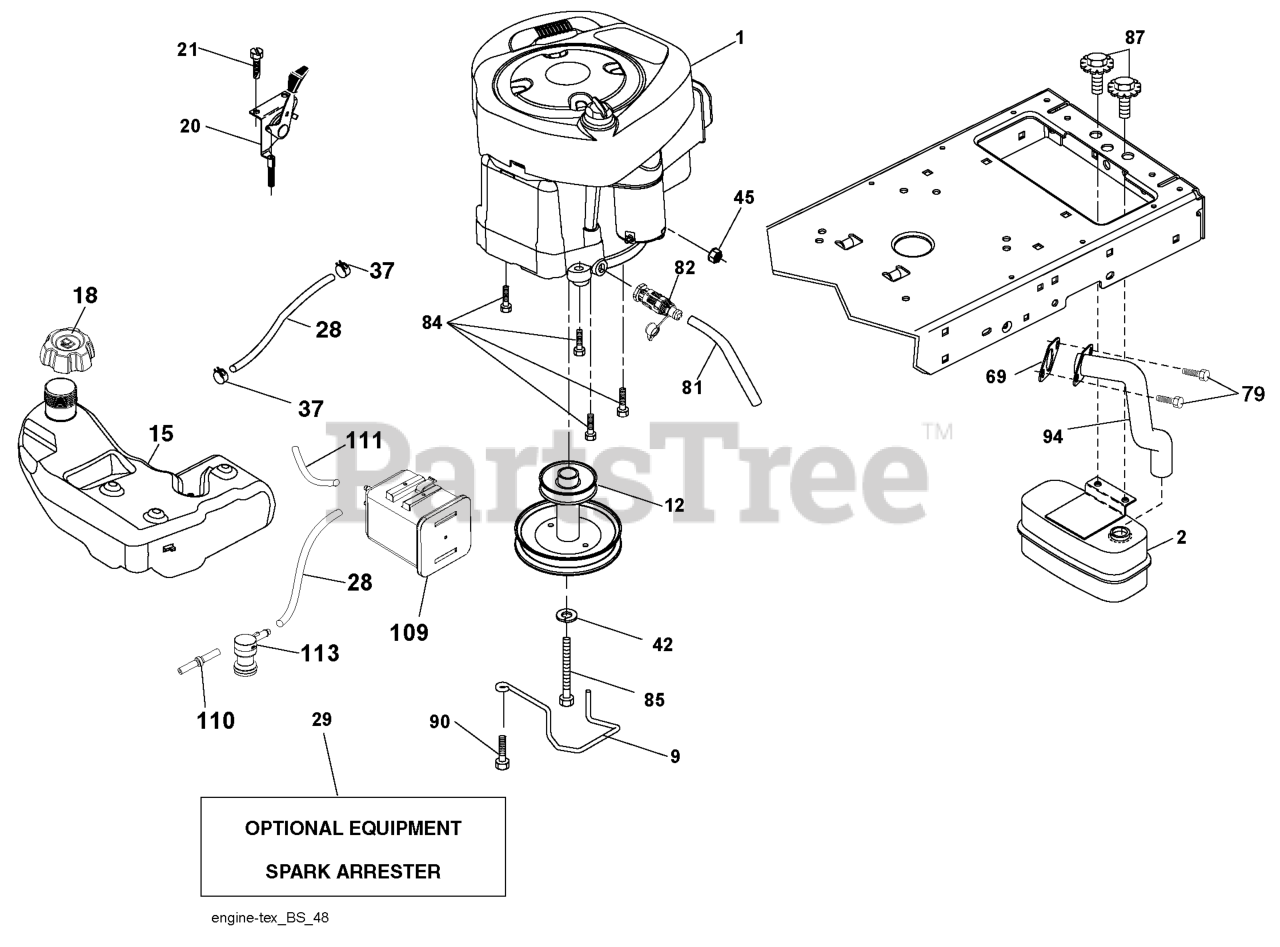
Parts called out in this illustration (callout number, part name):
2	MUFFLER.SINGLE.CYL.KOHL/B&S
9	KEEPER.BELT.ENGINE.4.2
12	PULLY ENGINE
15	TANK.ASM.FUEL.3GA.CARB
18	RP CAP ASM
20	CONTROL.TH/CK.COBRA.KO
21	SCREW.#10 X 0.750.BOS
28	LINE.FUEL.64"REAR.EMIS
29	KIT.SPARK ARRESTOR 794945 B&S
37	HOSE CLAMP
42	LOCKWASHER
45	NUT
69	REPL BY 532 27 22-93
79	SCREW.SOCKET HD.5/16-1
81	TUBE, DRAIN OIL ASM.
82	VALUE.OIL.DRAIN
84	SCREW.3/8-16
85	BOLT HEX 7/16-20X4-1/4"
87	BOLT.5/16-18UNCX3/4 W/SEMS.BLK
90	SCREW 3/8-16X1
94	EXHAUST.TUBE.B&S.
109	CANNISTER, CARBON
110	VALVE.ASM.ANTI-SLOSH
111	RP PURGE LINE
113	VALVE.SLANT.CARTRDG.90 DEG.TEX
